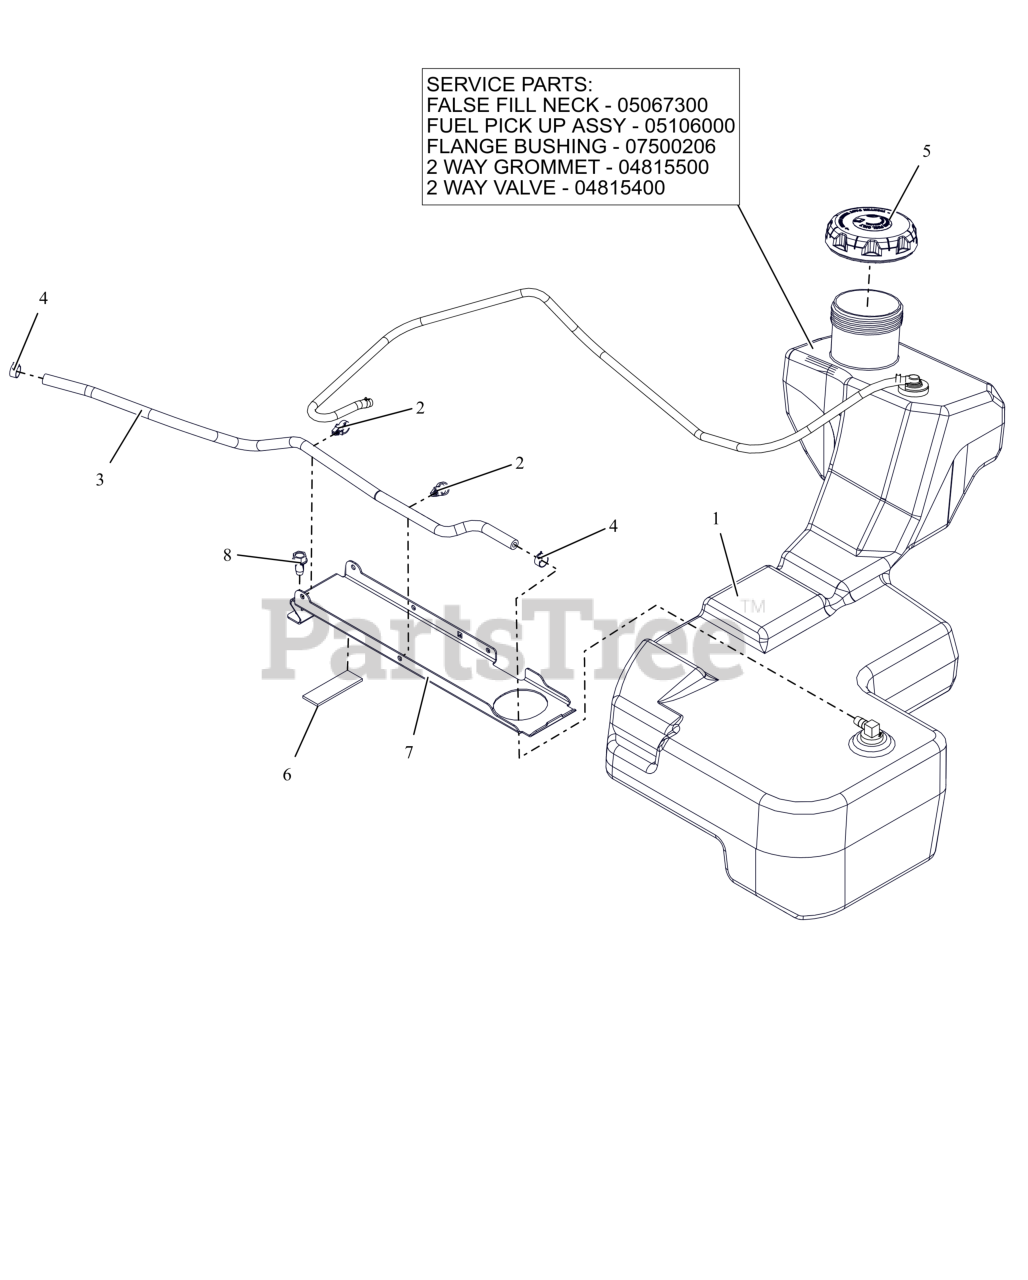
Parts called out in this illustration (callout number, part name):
1	ASM, FUEL TANK-HD
1	INSERT, FUEL NECK FALSE FILL
1	ASM, HD FUEL PICK-UP
1	BSHG-FLG .375X1.062X.625 NITR
1	GROMMET, 2-WAY
1	VALVE, 2-WAY
2	ROUTING CLIP (1/2" ID)
3	HOSE, .25 LOW-PERM BULK GAS
4	CLAMP, FUEL LINE
5	CAP, FUEL VENTIN AUTOLOCK
6	PAD,RBR 1.0"X3.0" W/ADHESIVE
7	BRKT, FUEL TANK HOLD DOWN
8	SCR,TAP .375-16X.75 HWH TR ZCC
